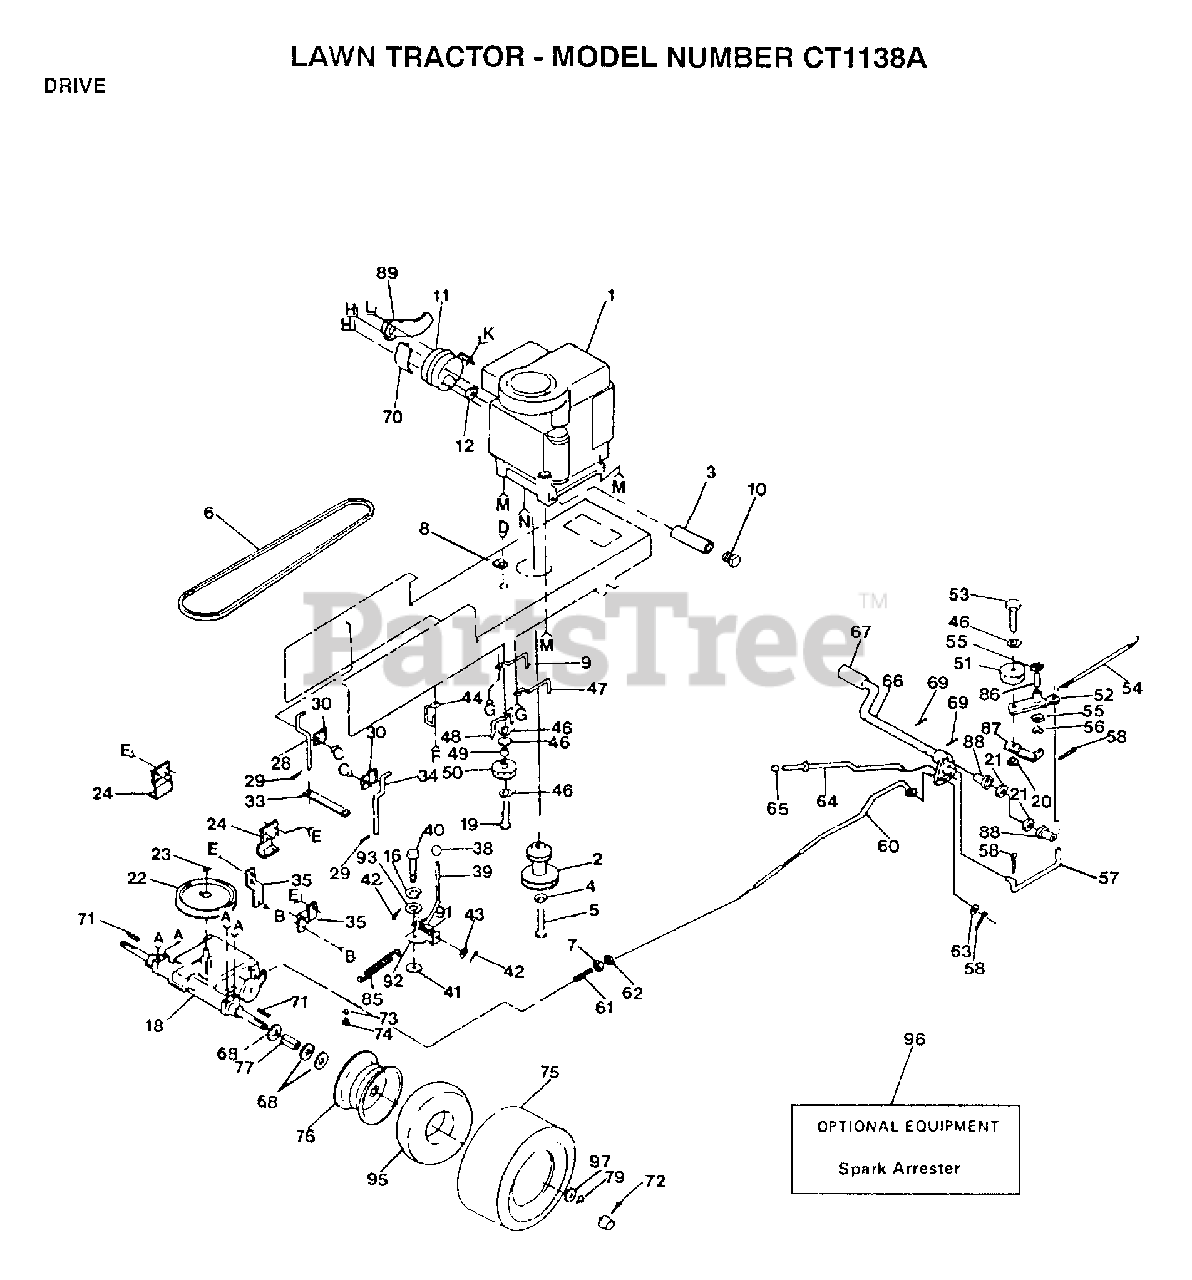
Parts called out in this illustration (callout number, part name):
1	ENGINE BRIGGS AND STRATTON
4	LOCKWASHER
5	BOLT
6	BELT-V.90.0.GD.DR
7	NUT
8	CLIP T
9	KEEPER BELT ENGLH
11	MUFFLER LTV
19	BOLT
21	WASHER LT
22	PULLEY TRANS
24	BRACKET LT
28	KEEPER BELT LH
29	SPRING.RETAINER
30	CLAMP LT
33	STRAP LOCATOR
34	KEEPER BELTRH
35	STRAP TORQUE
38	CONTROL KNOB LT
39	ROD SHIFTER
41	WASH-SHFT PLT LT
42	PIN COTTER 1/8
43	WASHER
46	WASHER
47	"KEEPER,BLT ENG LT"
48	BELT KEEPER LT
49	SPACER T
50	PULLEY.IDLER.FLAT
52	ARM IDLER
54	"SPRING, RETURN LT"
55	WASHER LT
56	KLIP RING
57	"LINK, CLUTCH T"
58	COTTER PIN
60	BRAKE ROD LT
61	SPRING ROD LT
62	NUT
63	WASHER
67	PEDAL COVER T
68	WASHER
70	SHIELD HEAT LTV
71	SQUARE KEY
72	HUB CAP
73	VALVE CAP
74	VALVE STEM LT
77	SPACER LT
79	E-RING LT
86	"LY, BEARING"
87	RETAIN BELT
88	NYLON BEARING
89	DEFLECTOR MUFFLER
91	SPRING LT
92	PLATE SHIFT LT
93	WASHER LT
95	TUBE.18X9.5-8
97	WASHER
